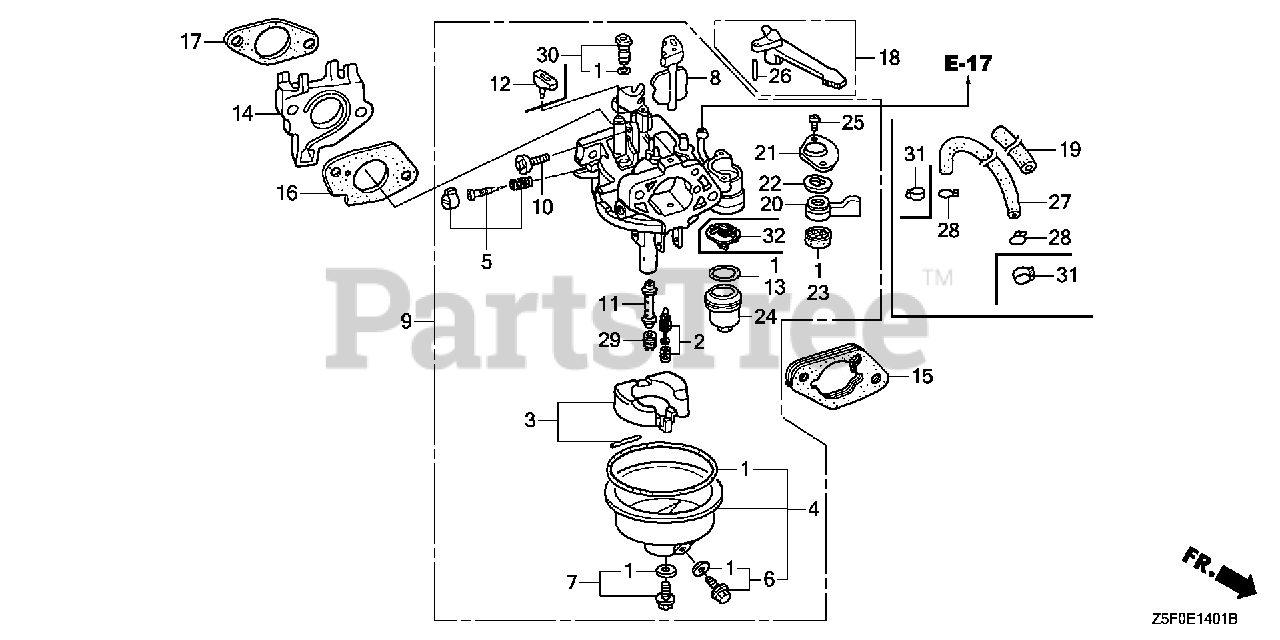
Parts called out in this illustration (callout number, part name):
1	GASKET SET (INCLUDE 16173-001-004) (INCLUDES 16173-001-004)
2	VALVE SET, FLOAT
3	FLOAT SET
4	CHAMBER SET, FLOAT
5	SCREW SET (Honda Code 4219879). (CARBURETOR NO.)
6	SCREW SET, DRAIN (Honda Code 1672187). (CARBURETOR NO.)
7	SCREW SET B
7	SCREW SET
8	CHOKE SET
9	CARBURETOR ASSY. (BE70B B)
10	SCREW, THROTTLE STOP
11	NOZZLE, MAIN (CARBURETOR NO.)
12	COLLAR, SET
13	GASKET, FUEL STRAINER CUP
14	INSULATOR, CARBURETOR
15	SPACER, CARBURETOR
16	GASKET, CARBURETOR
17	GASKET, INSULATOR
18	LEVER, CHOKE (STD)
20	LEVER, VALVE
21	PLATE, LEVER SETTING (CARBURETOR NO.)
22	SPRING, PETCOCK LEVER (CARBURETOR NO.)
23	GASKET, VALVE
24	CUP, FUEL STRAINER
25	SCREW, PAN (3X6)
26	PIN, SPRING (2X12)
29	JET, MAIN (#82)
29	JET, MAIN (#85) Use up to Engine SN BE81B B.
29	JET, MAIN (#88) Use up to Engine SN BE81B B.
30	JET SET, PILOT (#40)
30	JET SET, PILOT (#40) (ADVENTURE GREEN) (CARBURETOR NO.)
